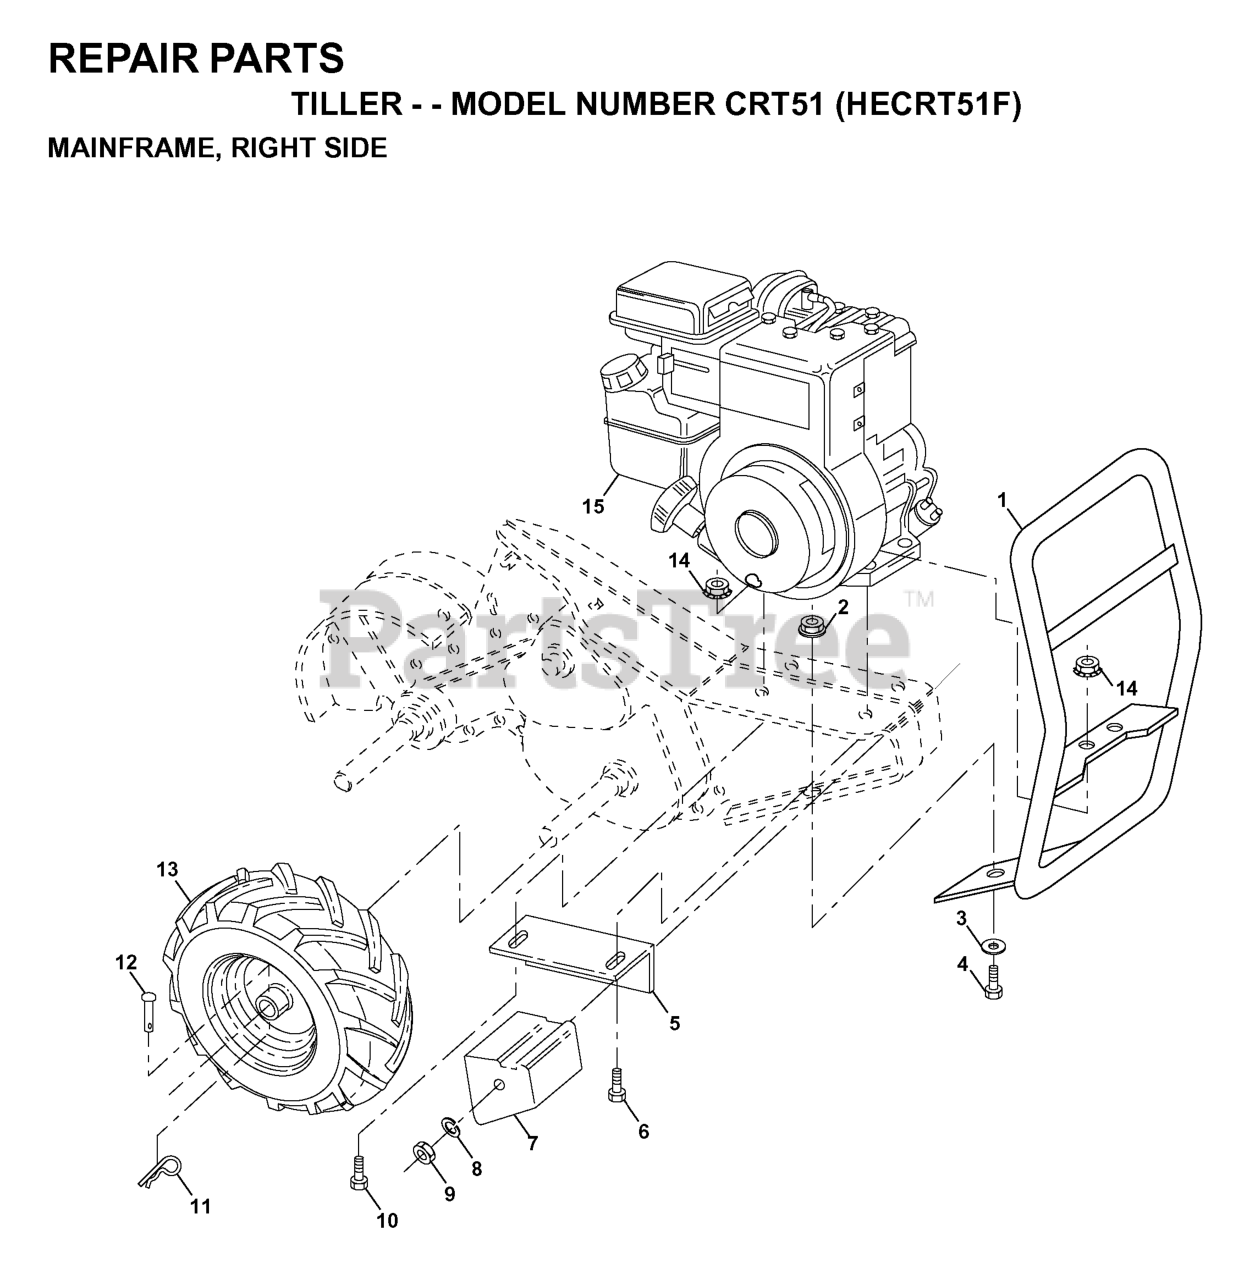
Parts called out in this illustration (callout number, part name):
1	BUMPER
2	LOCKNUT-FLANGE 5/16-18
3	WASHER
4	BOLT
5	DNO BRACKET RH CRT
6	Bolt Fin Hex 5/16 - 18 Unc x 2 Gr. 2
7	COUNTERWEIGHT, RH
8	WASHER, LOCK 3/8
9	NUT.HEX.3/8-16UNC
10	BOLT
11	RETAINER M
12	RIVET,DRILLED
13	TIRE.16X4-8.CHEVRON.TILLER
14	NUT
532124366	RIM
532124718	VALVE STEM LT
